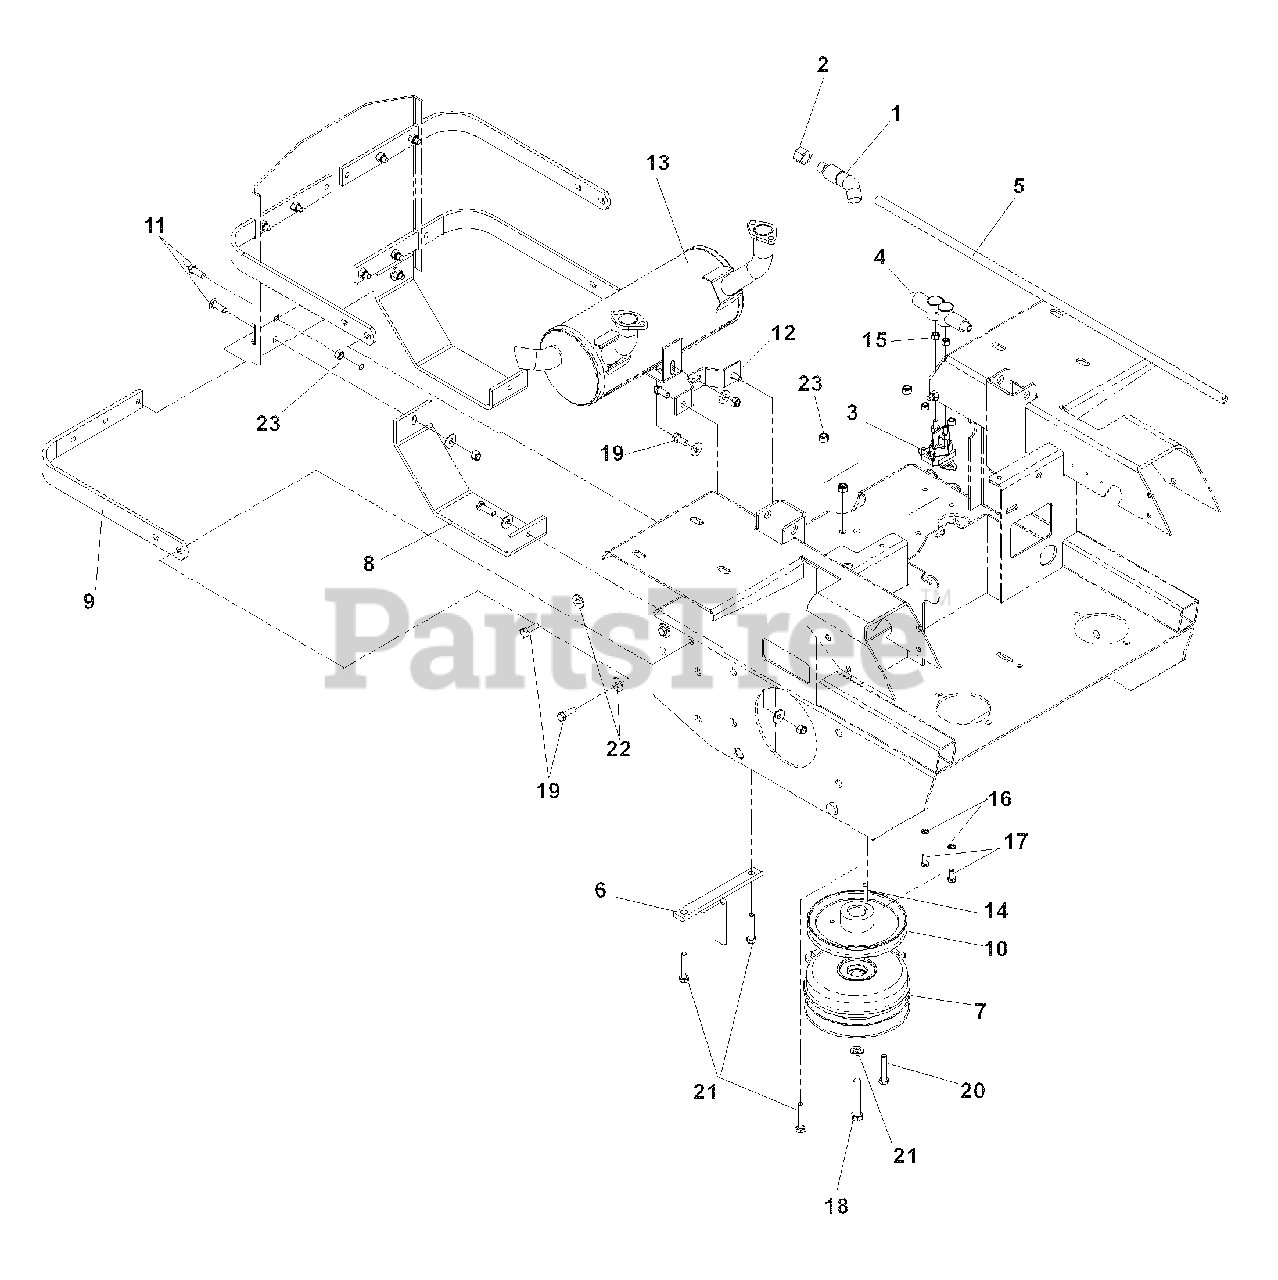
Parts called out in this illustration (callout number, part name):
1	HOSE-DRAIN
4	INSULATOR, BATTERY
5	FUEL LINE HOSE
6	CLUTCH TIE DOWN
8	SKID PLATE
11	RHSNB, 5/16-18 x 1
12	BRACKET, MUFFLER
14	KEY, 1/4 SQ x 1 1/4
15	NUT, 1/4-20, NYLOC
16	WASHER, 1/4
17	HCS, 1/4-20 x 5/8
18	HCS, 7/16-20 x 2 1/2
19	HCS, 5/16-18 x 1
20	LOCKWASHER, 7/16
21	HCS, 5/16-18 x 1 3/4
22	WASHER, 5/16
23	NUT, 5/16-18, NYLOC
